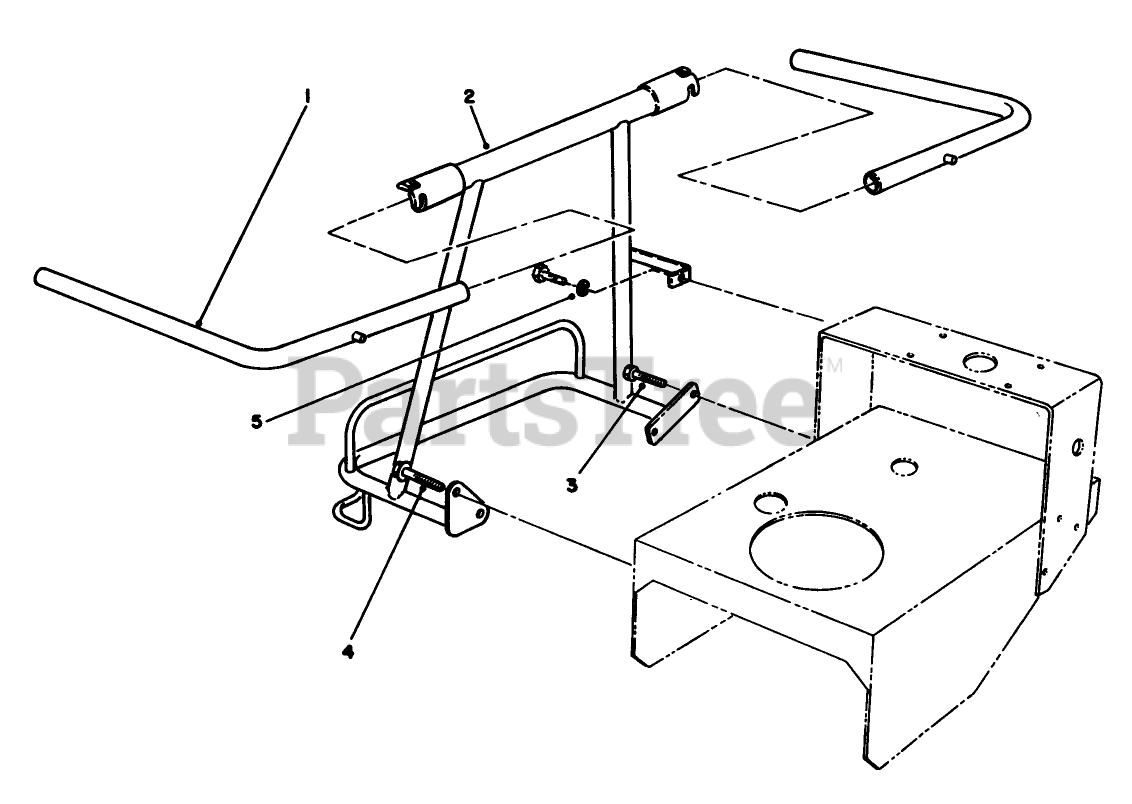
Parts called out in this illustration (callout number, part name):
1	Frame Bagger
2	Support-Bagger
3	SCREW-HH
4	SCREW-HHF
5	WASHER-FLAT
